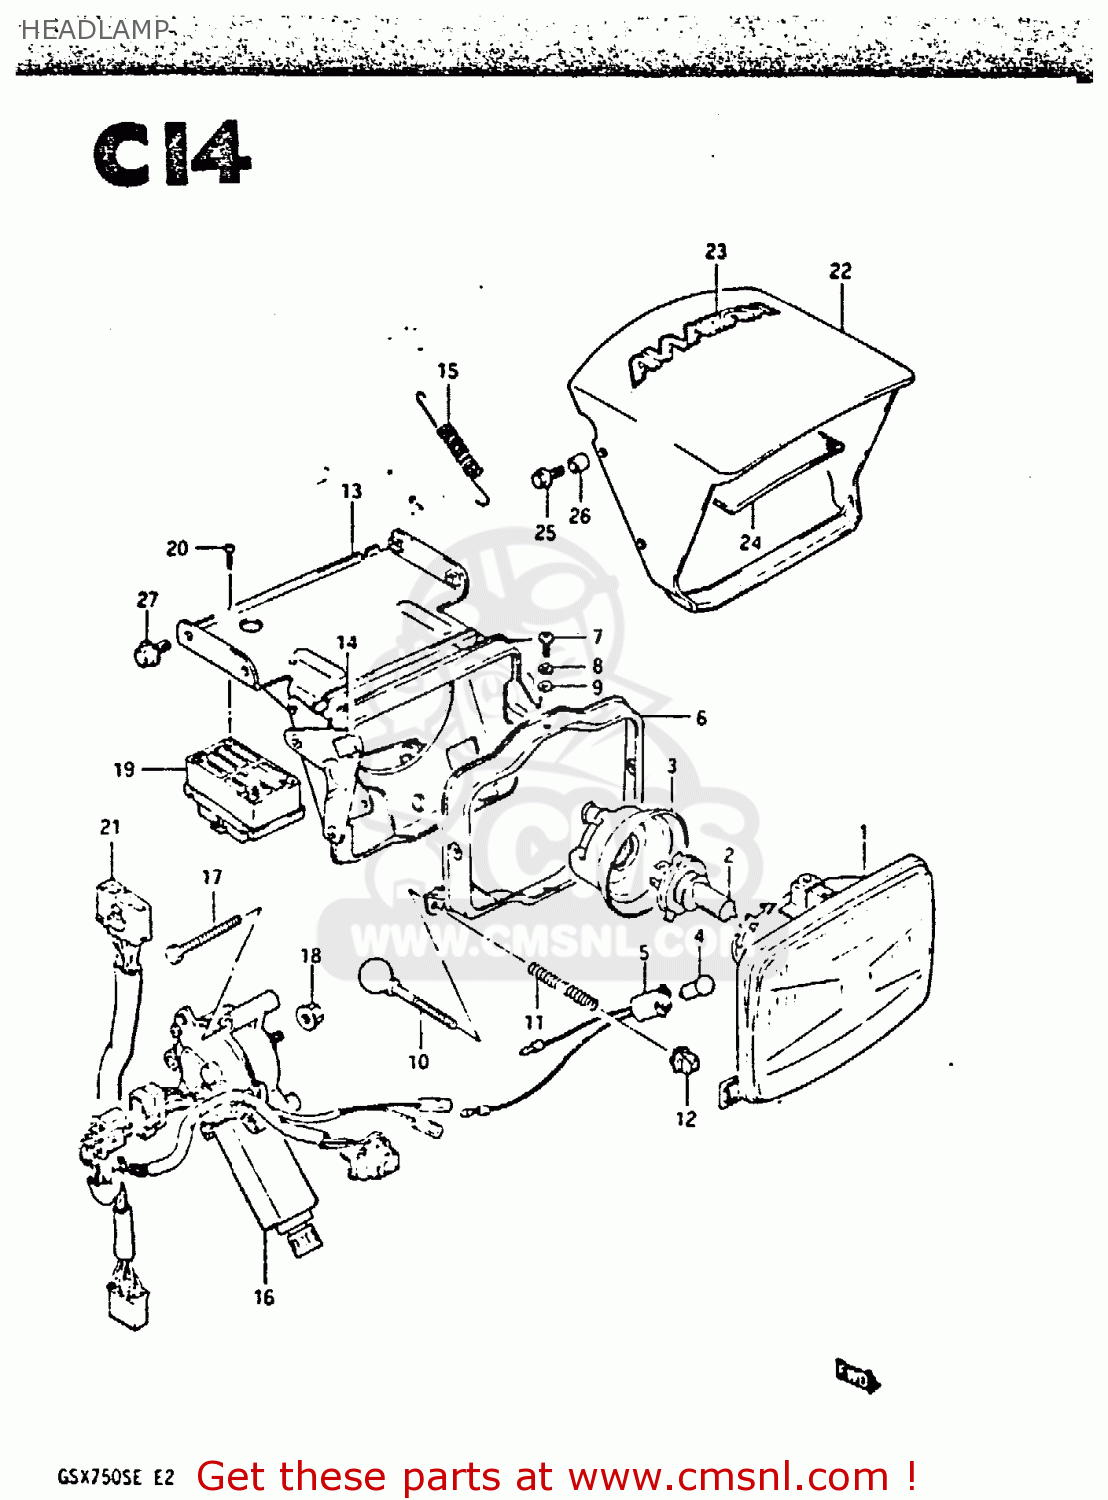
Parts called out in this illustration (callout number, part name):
1	UNIT
2	BULB(12V60/55W,H4)
3	COVER, SOCKET
4	BULB(12V3.4W,STANLEY,A72A)
5	SOCKET
6	RING, RETAINING
7	SCREW
8	WASHER,LOCK
9	WASHER,5MM
10	SCREW,ADJUSTER
11	SPRING
12	NUT
13	BRACKET, HEADLAMP
14	CUSHION
15	SPRING
16	MOTOR ASSY
17	BOLT 6X50
18	NUT
19	CONTROL UNIT
20	SCREW
21	CORD ASSY
22	COVER, HEADLAMP
23	EMBLEM, HEADLAMP COVER
24	SHEET, HEADLAMP COVER
25	BOLT
26	SPACER
27	BOLT
